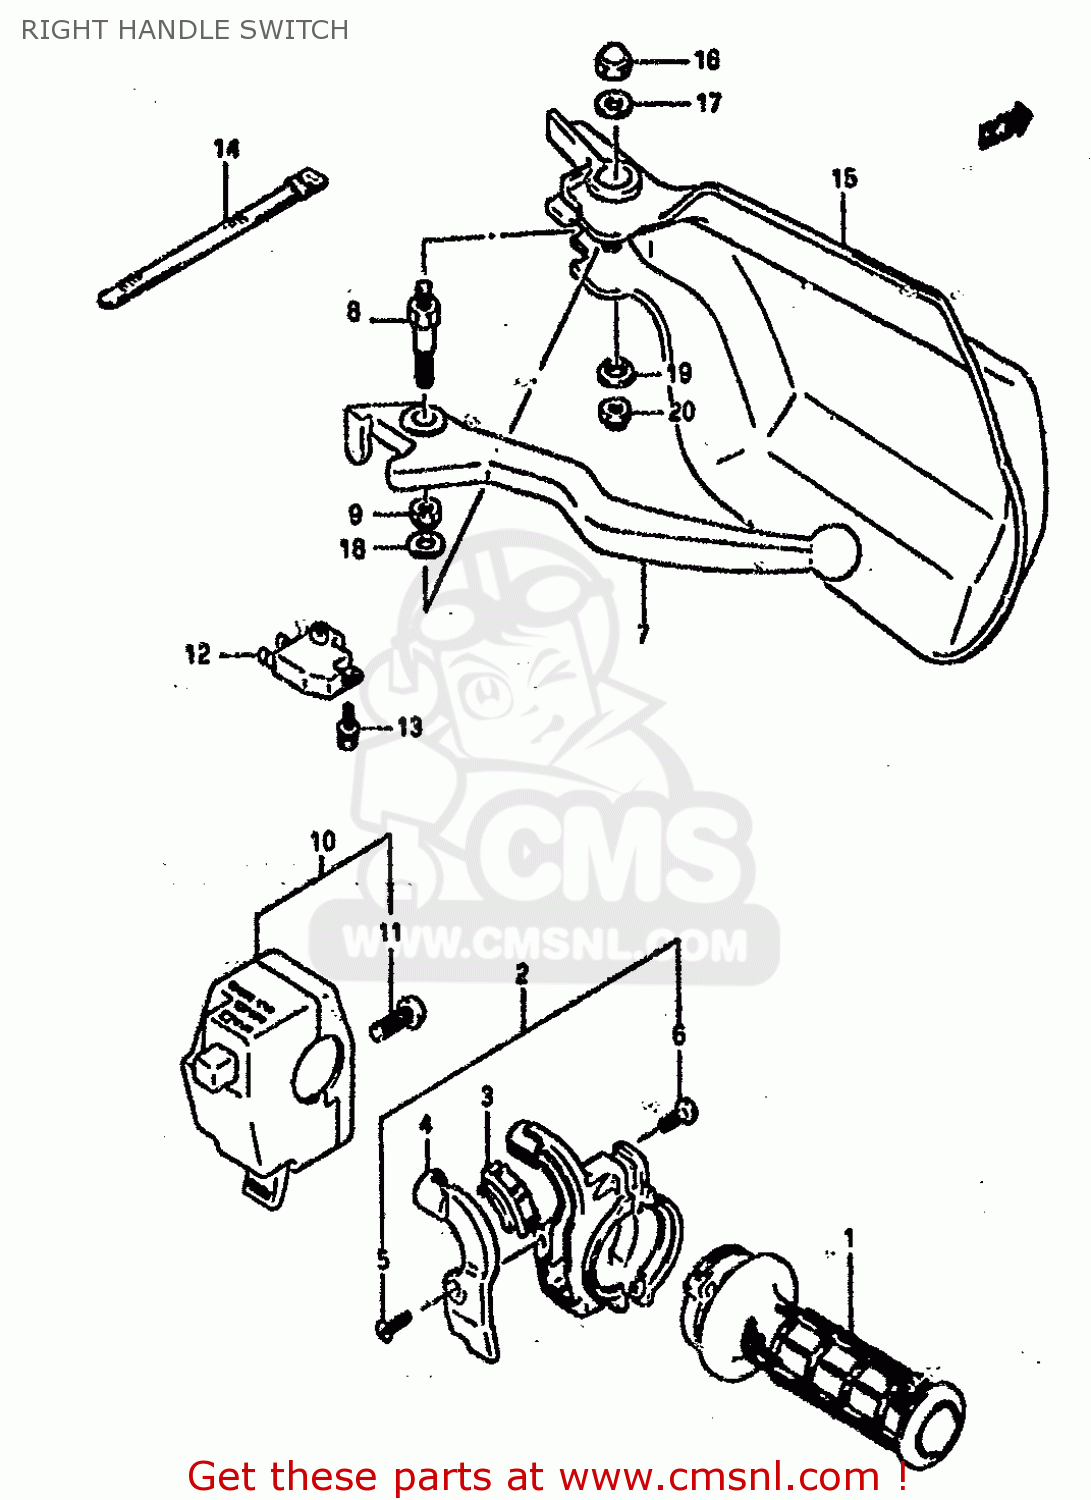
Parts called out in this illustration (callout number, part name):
1	GRIP,THROTTLE
2	CASE ASSEMBLY,THROTTLE
3	GUIDE PIECE,THROTTLE
4	COVER,THROTTLE CASE
5	SCREW 4X10
6	SCREW
7	LEVER,BRAKE
8	BOLT,BRAKE LEVER PIVOT
9	NUT
10	SWITCH ASSY,HANDLE RH
11	SCREW
12	SWITCH ASSEMBLY,STOP
13	SCREW
14	CLAMP(L:120)
15	COVER KNUCKLE
16	NUT 6MM
17	WASHER (6.5X20X1.6)
18	WASHER(6.5X16X1.2)
19	WASHER
20	NUT
